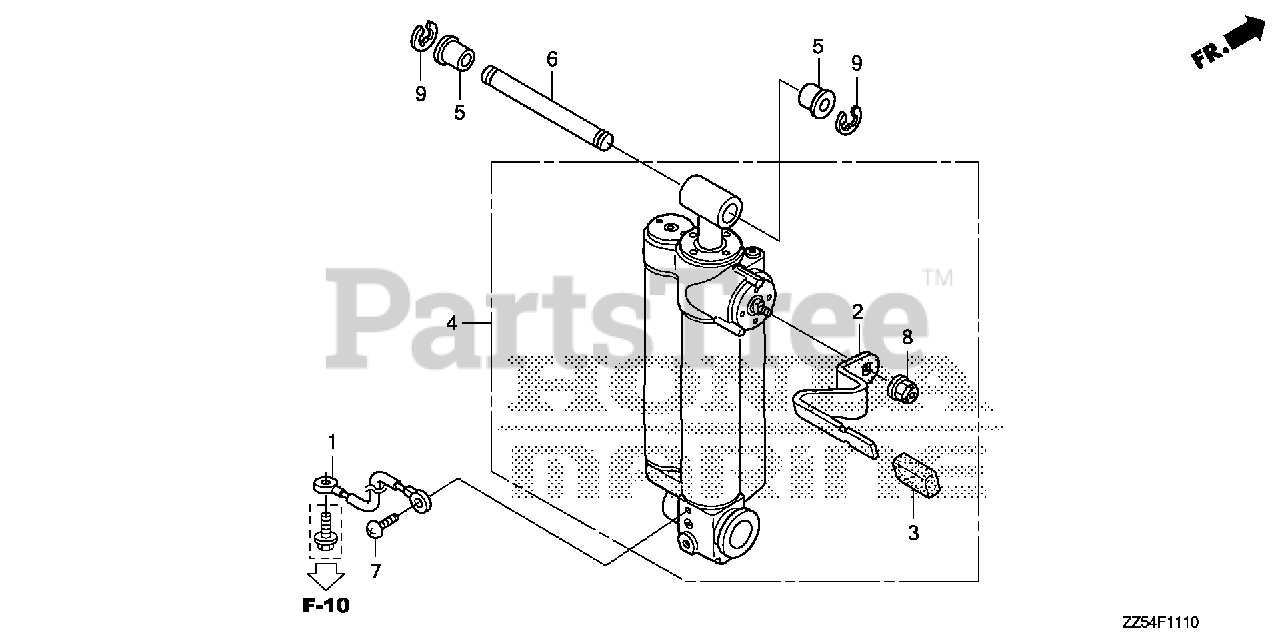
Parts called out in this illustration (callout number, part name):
1	WIRE, LEAD (1.5X116MM)
2	LEVER, TILT
3	GRIP, TILT LEVER
4	SHOCK ABSORBER ASSY.
5	BUSH, CYLINDER (UPPER)
6	PIN, CYLINDER (UPPER)
7	SCREW, PAN (6X8)
8	NUT, SELF-LOCK (6MM)
9	E-RING (10MM)
